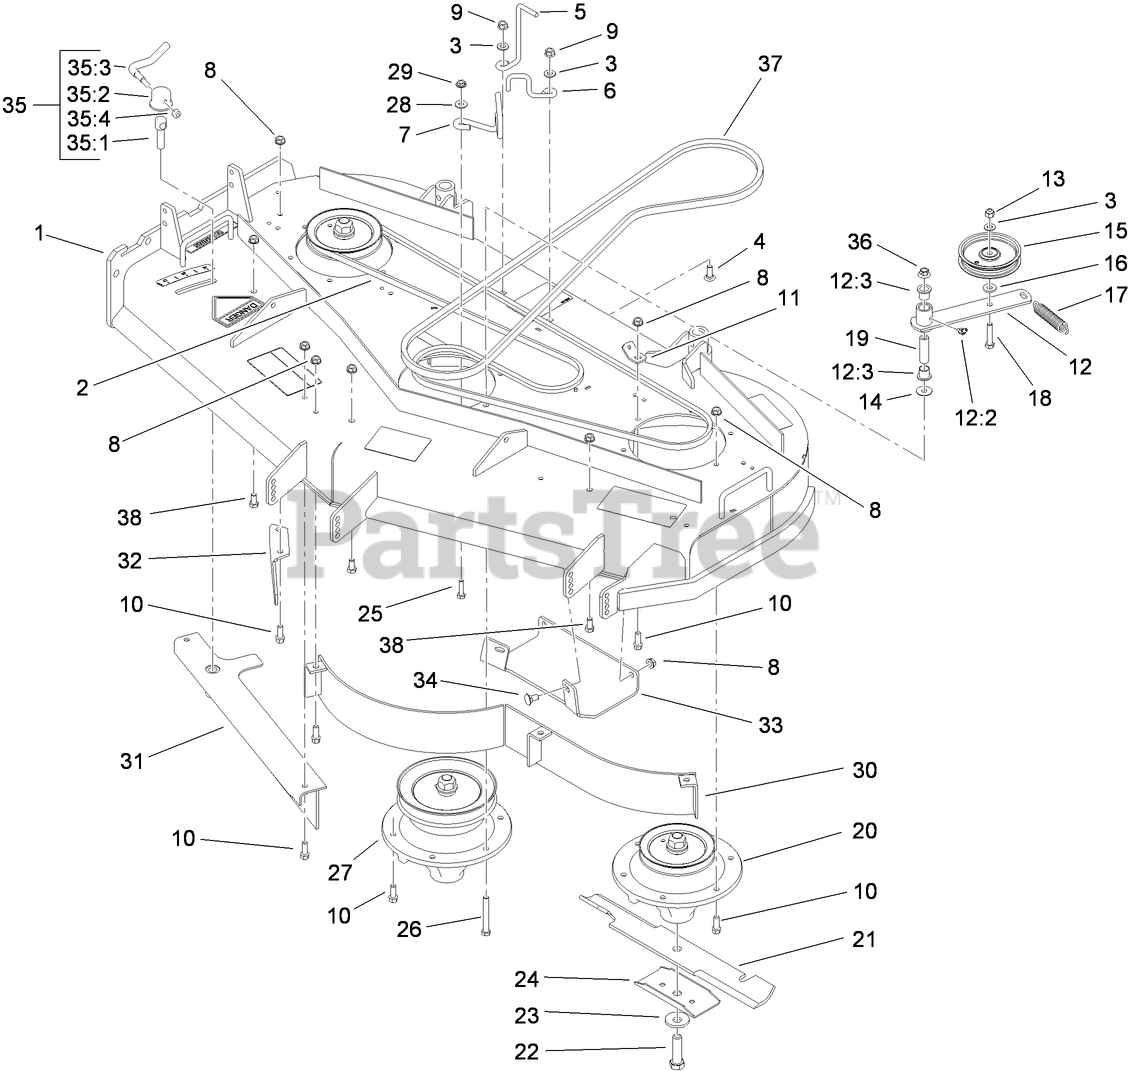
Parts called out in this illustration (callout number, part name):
1	DECK ASM
2	BELT-V
3	WASHER-FLAT
4	SCREW-CARR
5	GUIDE-BELT
6	GUIDE-BELT
7	GUIDE-BELT
8	NUT-HHF, WHIZ
9	NUT-HF
10	SCREW-HWH
11	PLATE-SPRING
12	IDLER ARM ASM
12:2	FITTING-LUBE, 45 DEG
12:3	BUSHING-FLANGE
13	NUT-LOCK, NI
14	WASHER
15	PULLEY-IDLER
16	WASHER-SPACER
17	SPRING-EXTENSION
18	SCREW-HH
19	SPACER
20	SPINDLE ASM
21	BLADE-18IN, HI FLOW
22	SCREW-BLADE
23	Washer-Blade Bolt, Heavy
24	STIFFENER-BLADE
25	SCREW-HH
26	SCREW-HH
27	SPINDLE ASM
28	WASHER-FLAT
29	NUT-HF
31	ADJUSTABLE BAFFLE ASM
32	BAFFLE-DISCHARGE
33	Plate-Skid
34	SCREW-CARR
35	LEVER ASM
35:1	Screw-Lock
35:2	CAP-LOCK
35:3	Lever-Lock
35:4	NUT-LOCK, NI
36	NUT-HF
37	BELT-V
38	SCREW-HH
